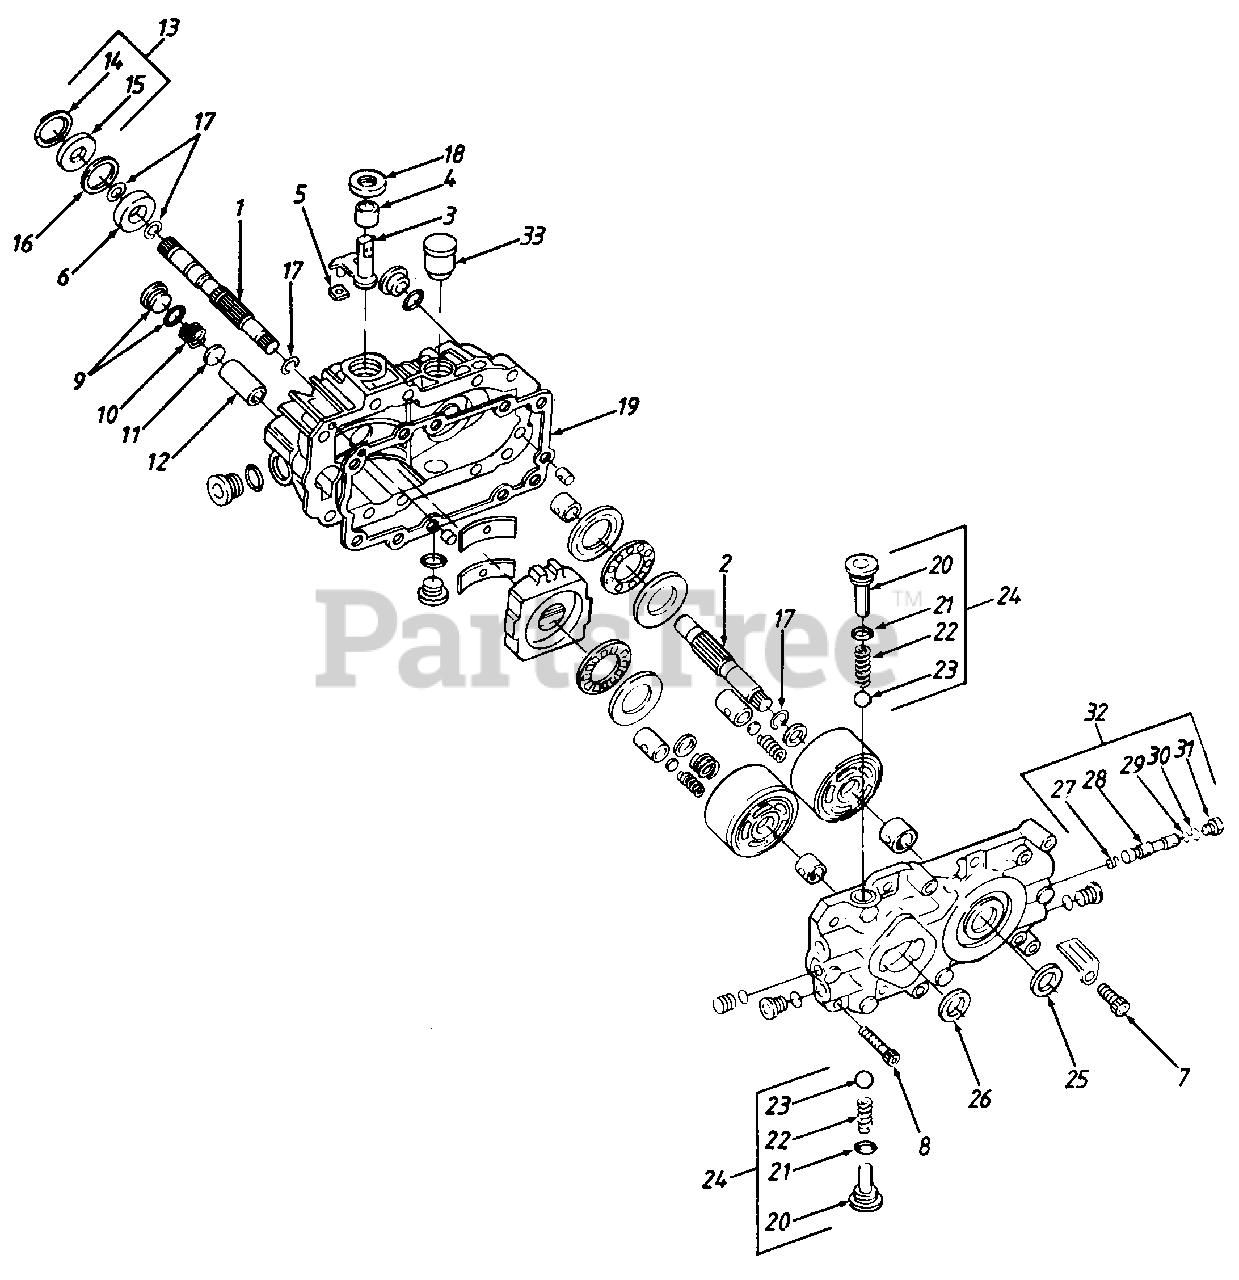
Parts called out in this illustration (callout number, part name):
1	Shaft-Pump
2	Shaft-Motor
3	Arm, Trunnion
4	Bearing, Journal
5	Guide, Slot
6	Bearing, Ball
7	Screw, Socket Head
8	Screw, Socket Head
9	Plug
10	Spring, Filter
11	Washer, Filter
12	Filter
13	Kit, Seal
14	Ring, Retaining
15	Seal, Lip
16	Spacer
17	Ring, Retaining
18	Seal, Lip
19	Gasket
21	O-Ring
22	Spring
24	Kit, Check Valve
25	Seal, Lip
26	Seal, Lip
27	Spring
28	Spool, Bypass
29	O-Ring
30	O-Ring
32	Kit, Bypass Valve
33	Reservoir
